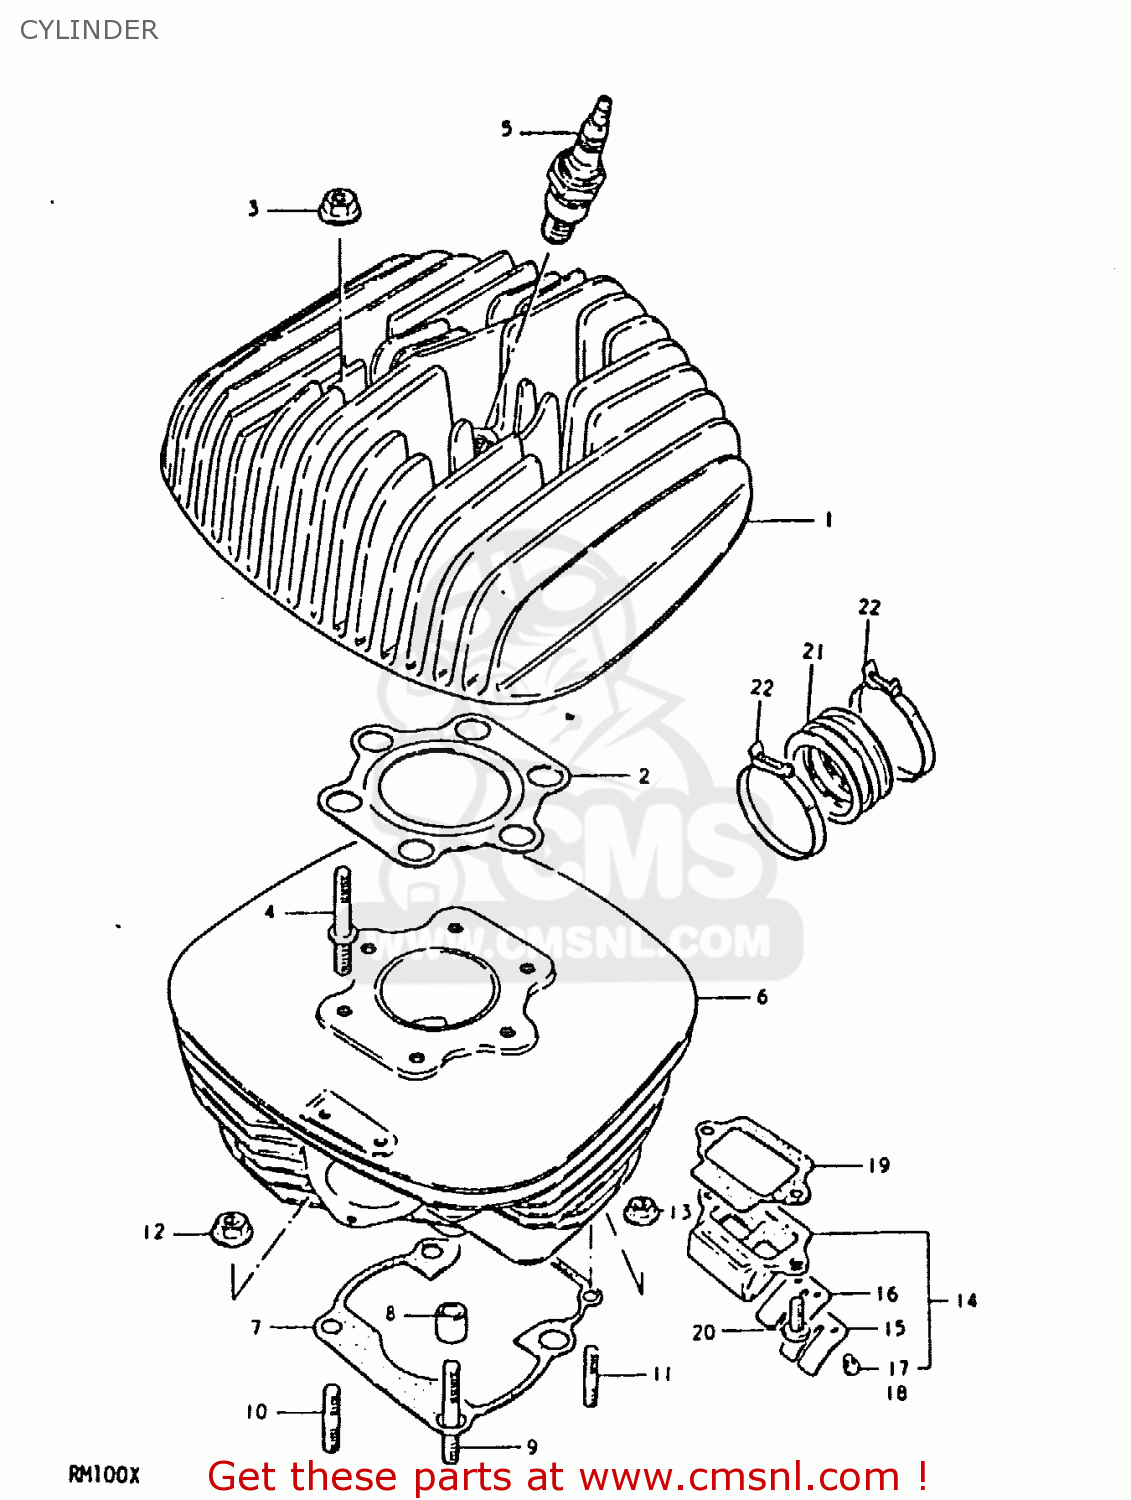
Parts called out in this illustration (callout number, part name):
1	HEAD,CYLINDER
2	GASKET,CYLINDER HEAD (NAS)
3	NUT
4	BOLT,STUD
5	SPARK PLUG
6	CYLINDER
7	GASKET,CYLINDER (MCA)
8	PIN
9	STUD 8X40
10	STUD 8X25
11	STUD 6X20
12	NUT
13	NUT
14	VALVE ASSY,REED
15	STOPPER,REED VALVE
16	VALVE,REED
17	SCREW
18	LOCK WASHER
19	GASKET,REED VALVE (MCA)
20	SCREW
21	PIPE,INTAKE
22	CLAMP
